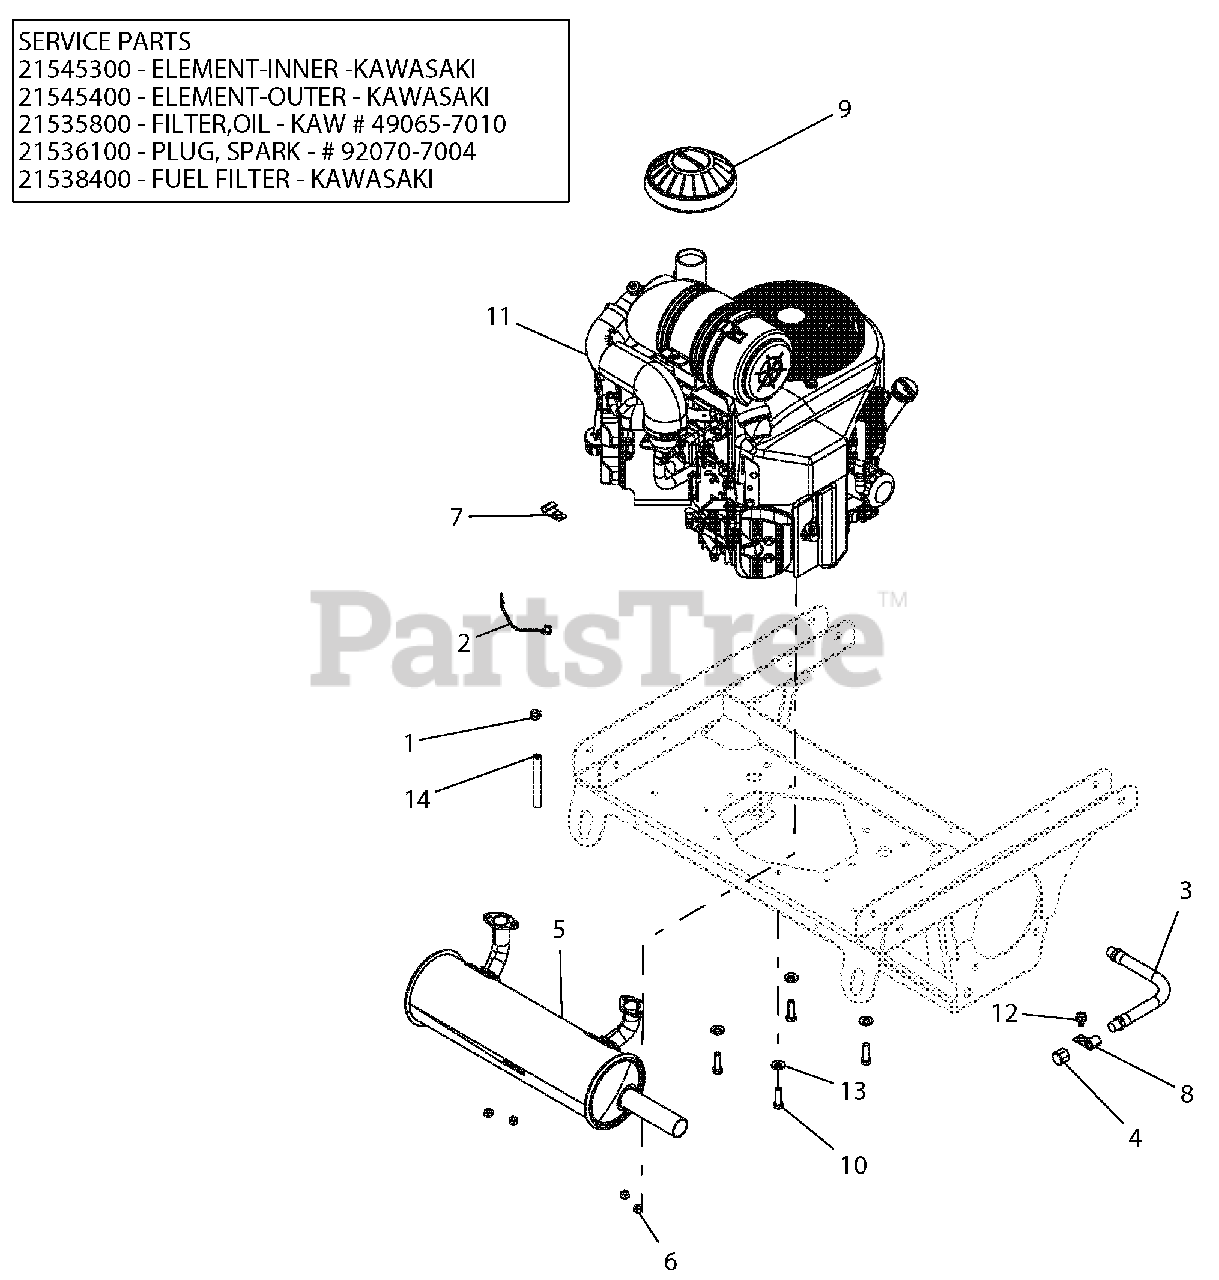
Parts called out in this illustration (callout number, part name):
1	CLAMP, FUEL LINE
2	LEAD - STARTER SOLENOID
3	HOSE, HYD .38-11-0K M6N0-M6NO
4	PIPE, CAP 3/8 NPT FEMALE
5	MUFFLER, 27-31 FX KAW
6	NUT-LK-TOP M8-1.25 YWZC
7	CLAMP, J
9	CAP, AIR CLEANER INTAKE (2")
10	BLT-HEX .38-16X1.25 GR5 YWZC NYTORQ
11	ENGINE, KAWASAKI FX850
12	SCR-TAP .38-16X.50 HWH TR YWZ
13	WSHR, 3/8" SPRING DISC
14	.25 LOW-PERM GAS HOSE 18.00" LG - VALVE TO KAW FX751 OR FX850
